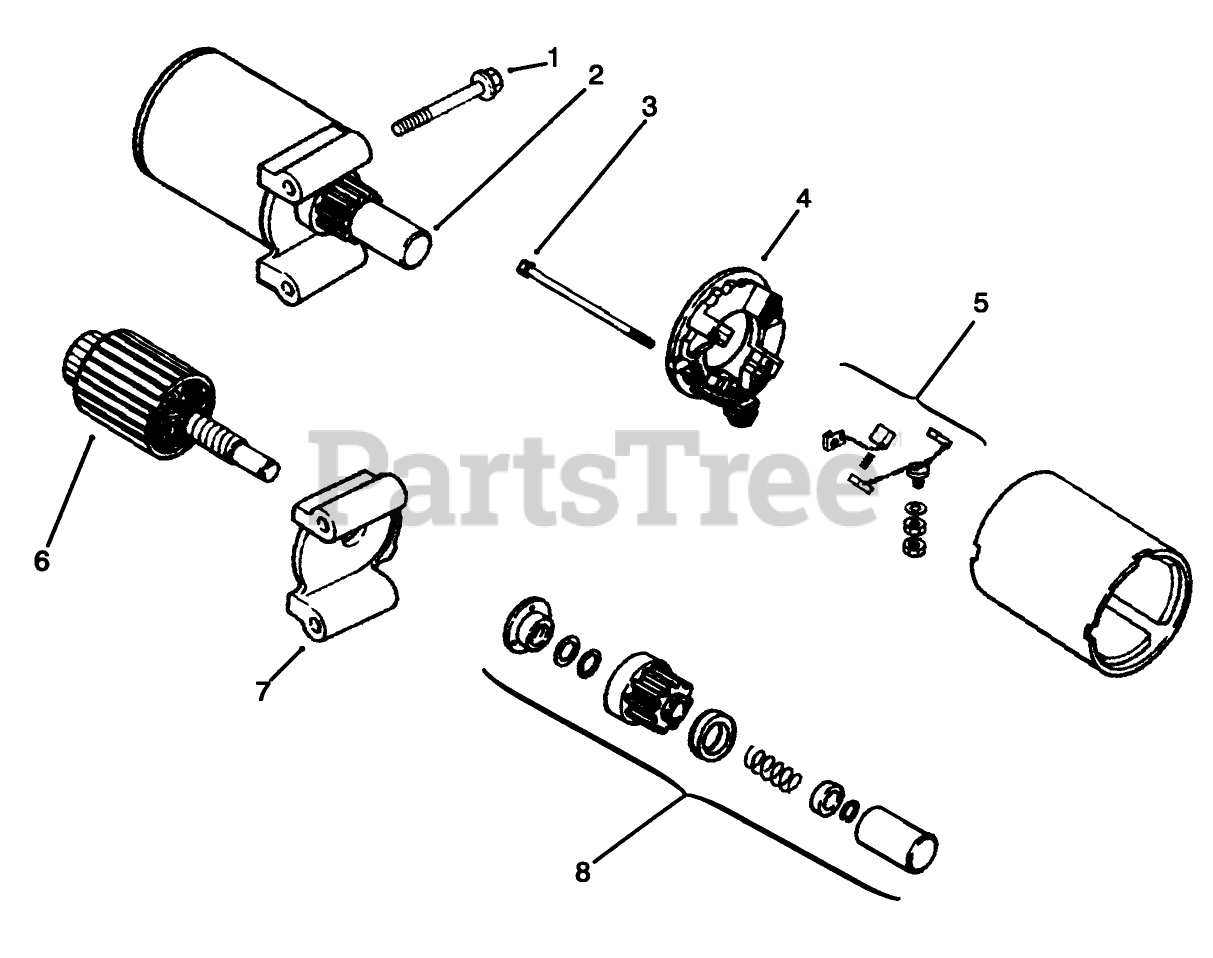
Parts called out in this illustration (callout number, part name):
1	Screw M8x1.25x70 (Only On: 72042, 72063, 72062, 72043)
2	Starter ASM Incl 3-8
3	Screw
4	Cap-Communtator Incl 5
5	Kit-Brush And Spring (Only On: 72042, 72063, 72062, 72043)
6	Armature-Starter
7	Cap-Drive End
8	Kit-Drive
